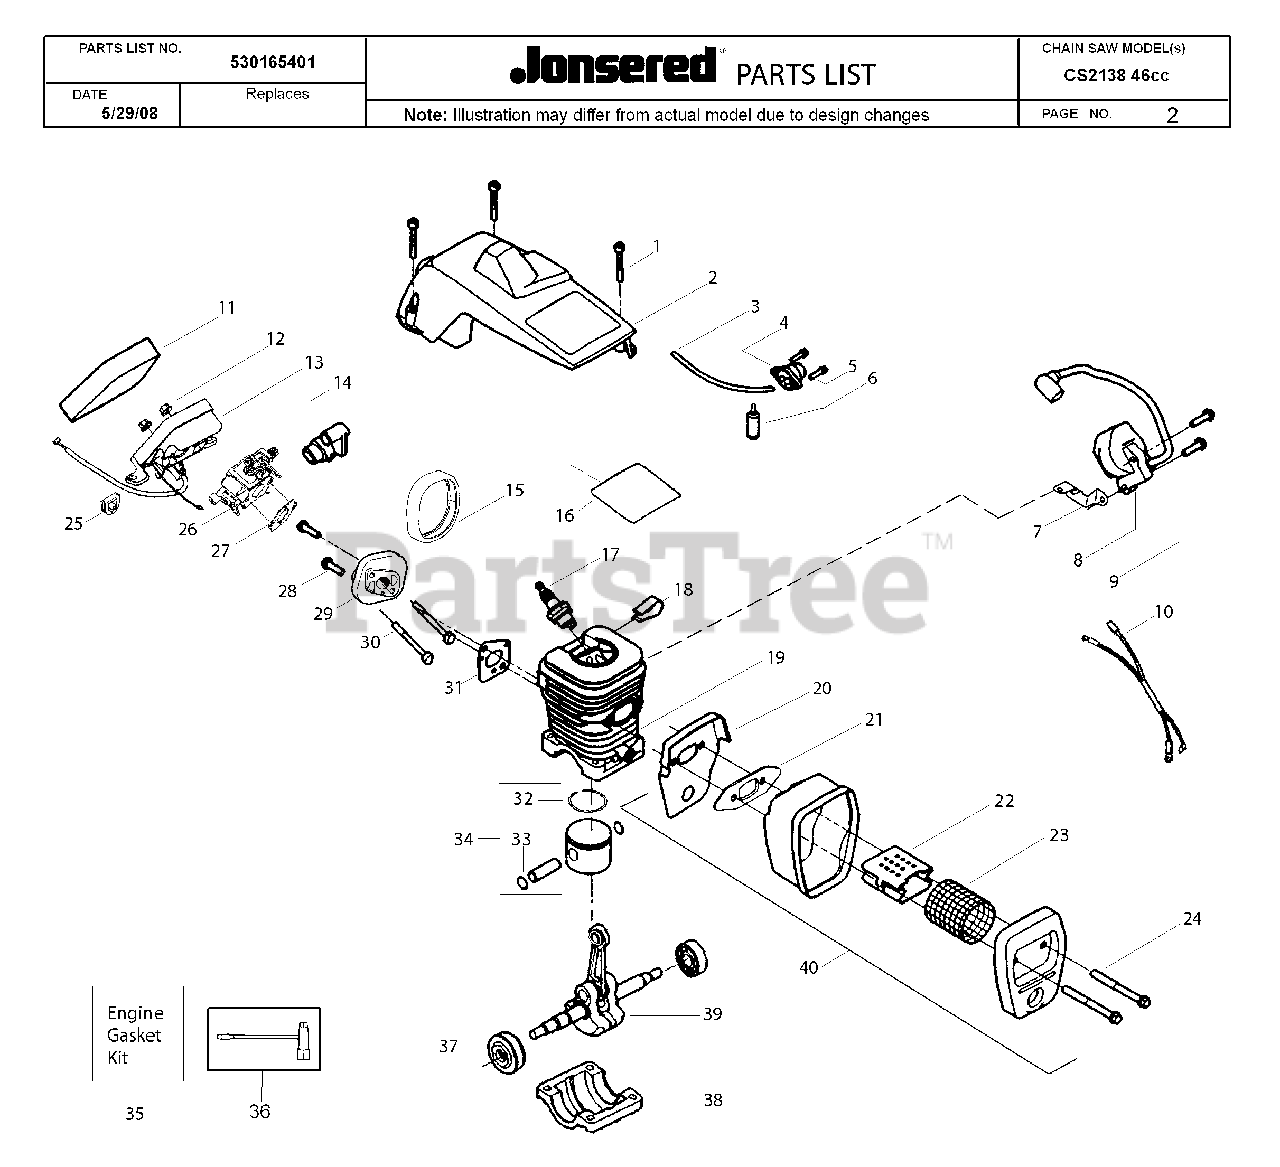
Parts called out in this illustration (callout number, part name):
6	FUEL PICK-UP ASSY
7	GROUND STRAP
10	WIRE HARNESS ASSY
11	AIR FILTER
13	ASSY-AIR BOX
14	GROMMET-CARB ADJUST.
17	SPARK PLUG (RCJ-7Y)
22	FLAME PROTECTION
29	PARTITION
33	C-CLIP,PSTN PIN 36/41
36	SCRENCH
37	BEARING & SEAL ASSEMBLY
40	MUFFLER
